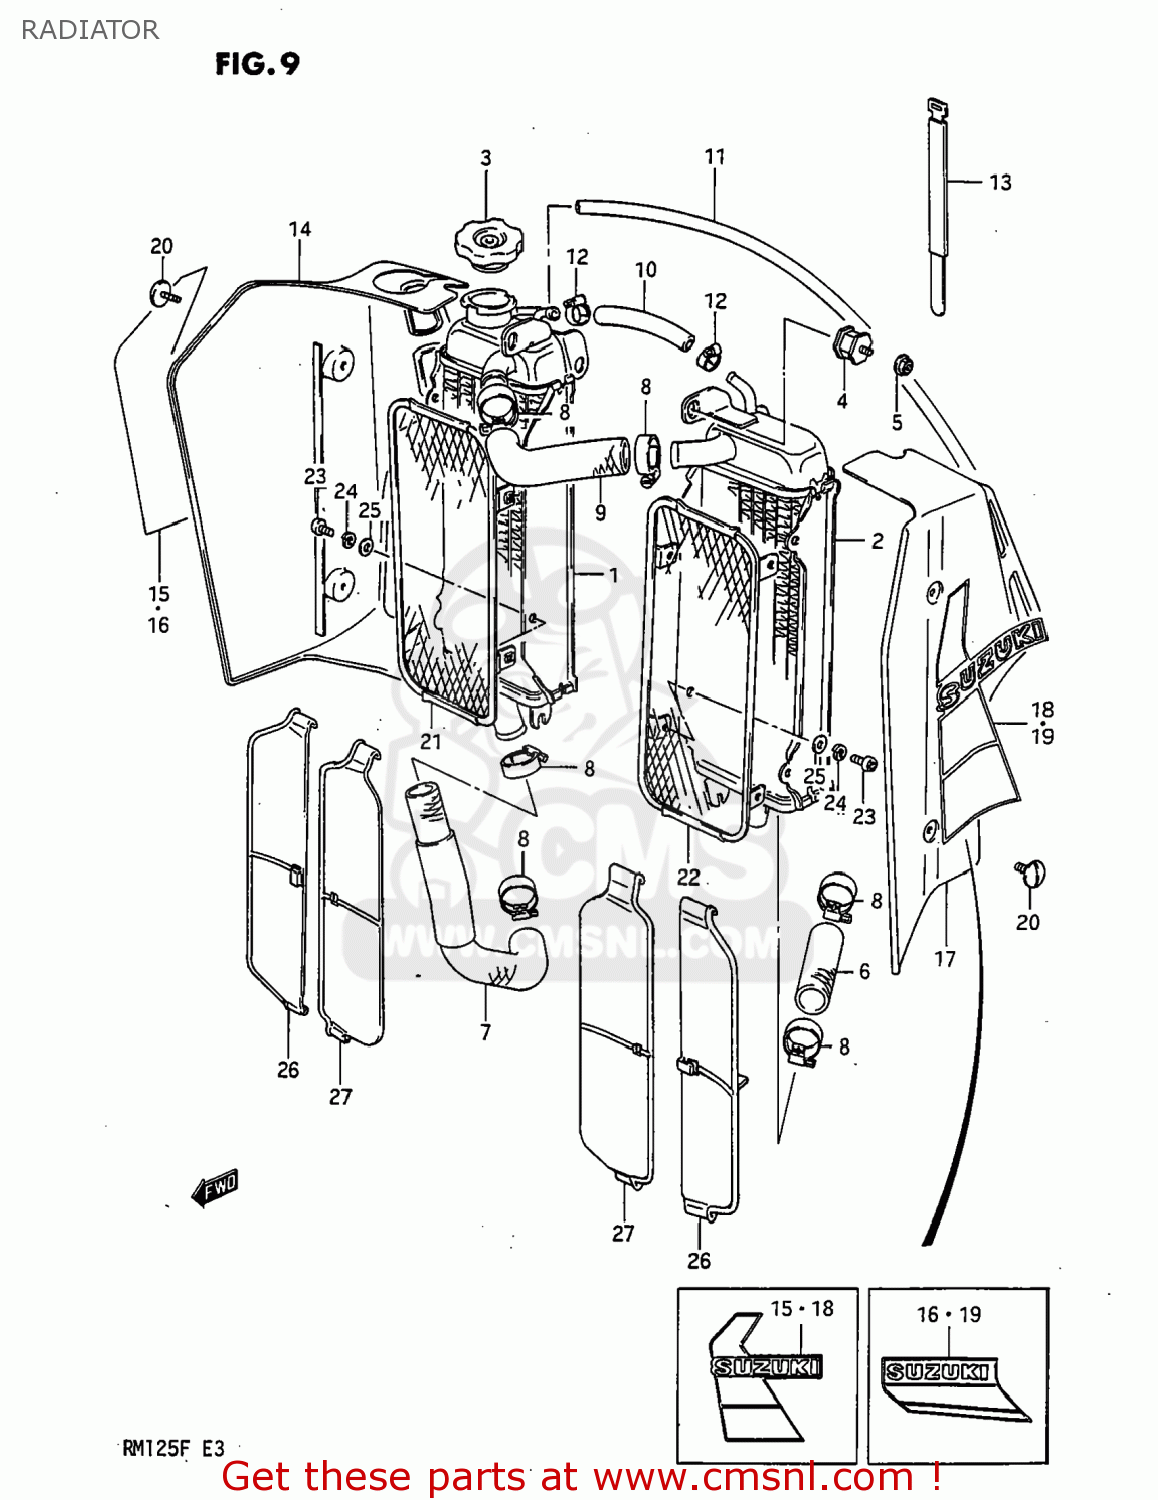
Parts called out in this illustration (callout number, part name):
1	RADIATOR ASSEMBLY,WATER
2	RADIATOR ASSEMBLY,WATER
3	CAP,RADIATOR
4	BOLT,RADIATOR CUSHION
5	NUT 6MM
6	HOSE,RADIATOR
7	HOSE,RADIATOR
8	CLAMP
9	HOSE,RADIATOR JOINT
10	HOSE,RADIATOR BY-PASS
11	HOSE
12	CLAMP
13	CLAMP
14	COVER,RADIATOR
15	TAPE SET
16	TAPE SET
17	COVER,RADIATOR
18	TAPE SET
19	TAPE SET
20	SCREW(6X14)
21	BUMPER,RADIATOR,RIGHT
22	BUMPER,RADIATOR,LEFT
23	SCREW
24	LOCK WASHER
25	WASHER
26	LOUVER,RADIATOR NO.1
27	LOUVER,RADIATOR NO.2
